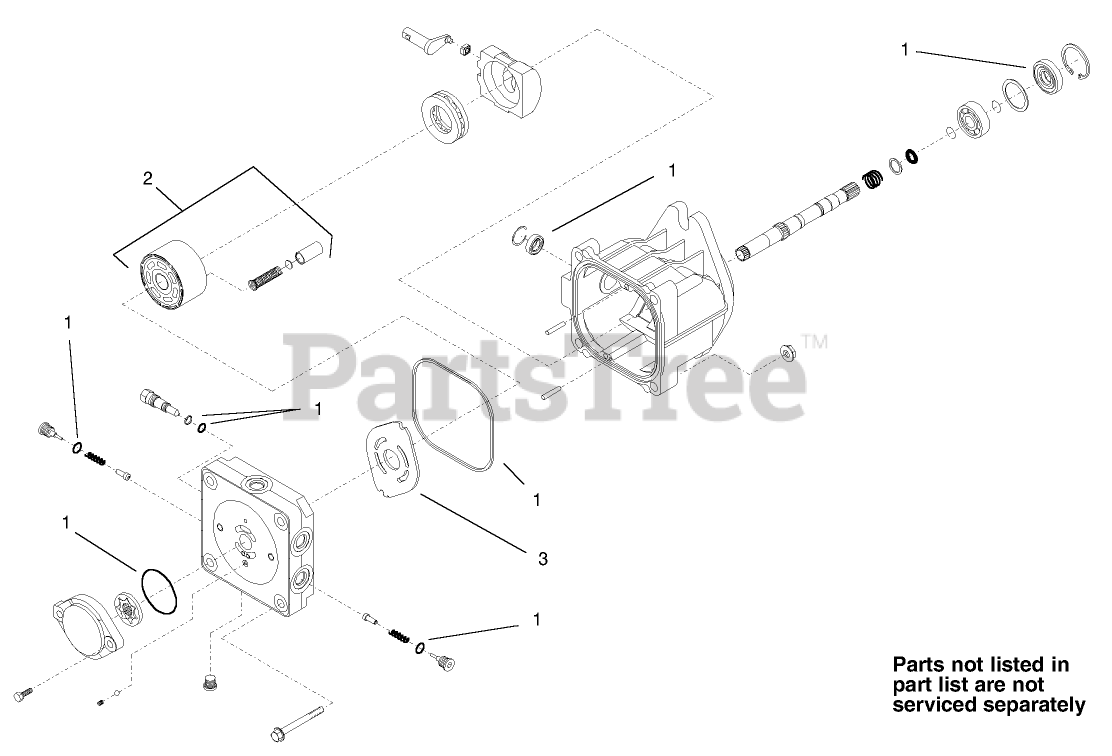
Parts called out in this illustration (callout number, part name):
1	OVERHAUL SEAL KIT
2	KIT-BLOCK, CYLINDER
3	PLATE-VALVE
